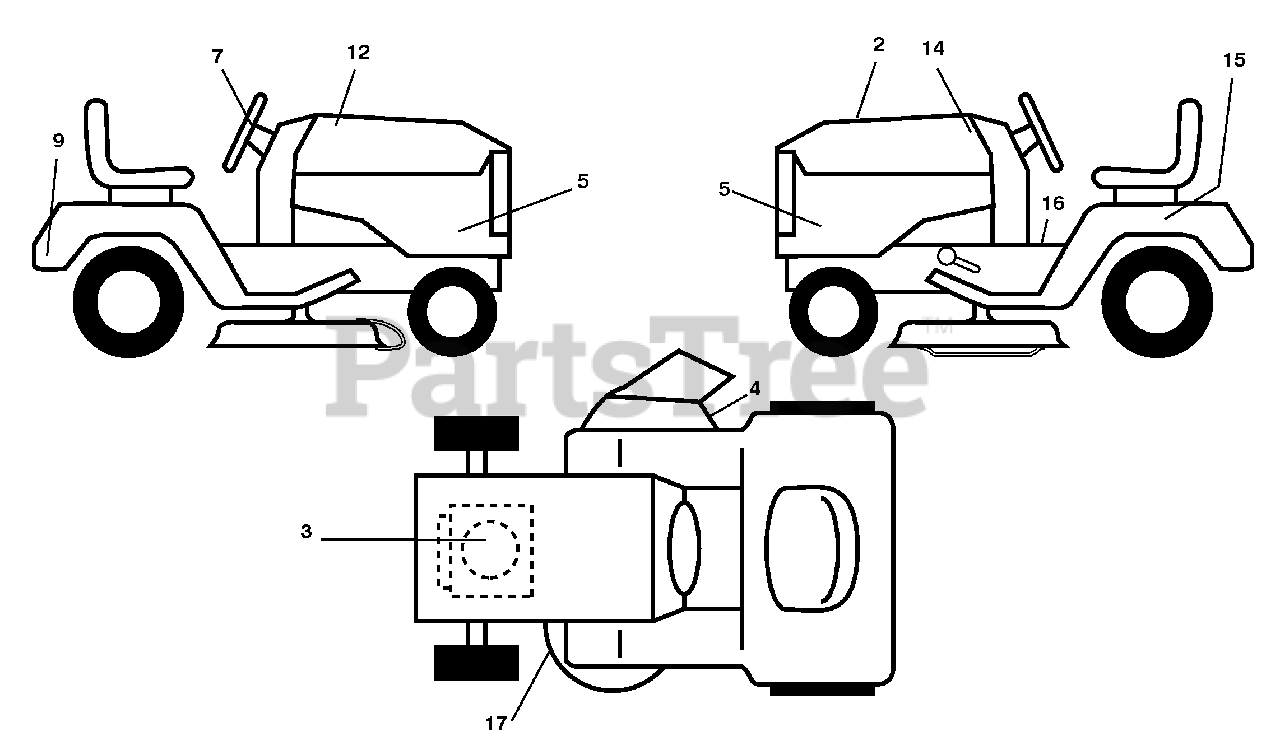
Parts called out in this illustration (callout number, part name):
2	Decal, Replacement
3	Decal, Engine HP
4	Decal, Warning
5	Decal, SDPNL
7	Decal, Ins Str Wh
9	Decal, Fender
12	Decal, Hood RH
14	Decal, Hood LH
15	Decal, Caution, Battery
16	Decal, Fender Warning
17	Decal, V-Belt Sch.
17	Decal, Handle Lft Height Adj.
17	Manual, Operator's E&F
17	Manual, Parts E&F
